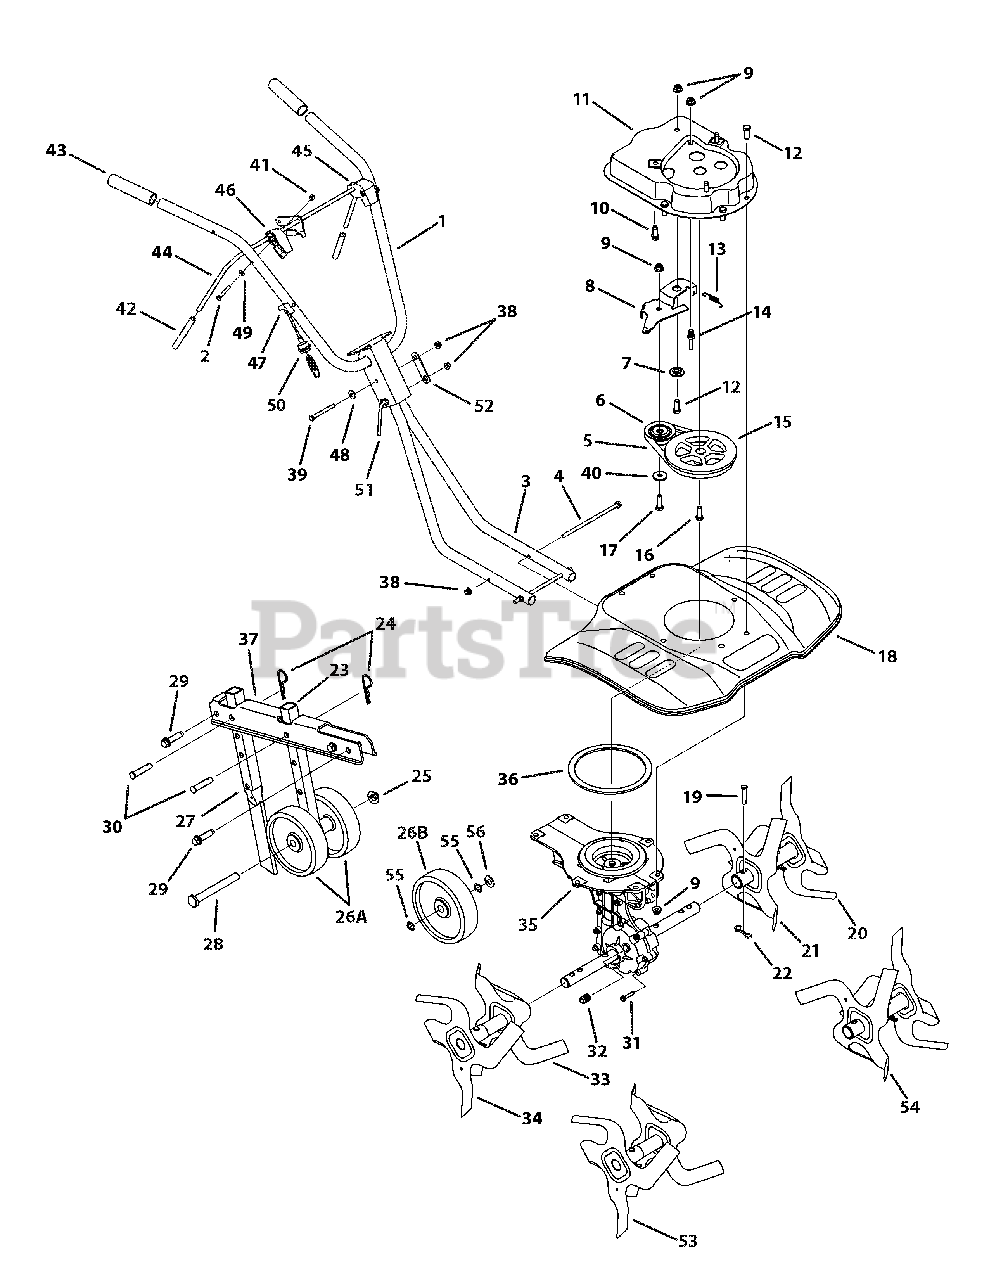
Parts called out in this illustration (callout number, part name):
1	Upper Handle
2	Hex Head Cap Screw, 1/4-20 x 1.75
3	Lower Handle
4	Flange Screw, 5/16-18 x 7.5, GR5
5	V-Belt
6	Idler Pulley
7	Shoulder Spacer
8	Idler Bracket
9	Flange Lock Nut, 3/8-16
10	Self Tapping Screw, 3/8-16 x 1.00
11	Belt Cover
12	Hex Head Cap Screw, 3/8-16 x 1.00
13	Extension Spring
14	Stud, 33 x 1.5, 3/8-16
15	Flywheel Pulley
16	Hex Head Cap Screw, 3/8-24 x 1.00
17	Hex Head Cap Screw, 3/8-16 x 1.55
18	Tine Shield 61 cm (model 240)
18	Tine Shield 40 cm (model 210)
19	Clevis Pin
20	Outer Tine Assbly LH (model 240)
21	Inner Tine Assbly LH (model 240)
22	Cotter Pin, Bow Tie
23	Rear Wheel Tube
24	Cotter Pin
25	Push Cap
26A	Wheel 5 x 1.38 (model 240)
26B	Wheel 6 x 1.50, Steel (model 210)
27	Depth Stake Tube
28	Axle Shaft
29	Self Tapping Screw, 3/8-16 x 1.50
30	Clevis Pin
31	Self Tapping Screw, 1/4-20 x 1.25
32	Pipe Plug, 1/4-18 NPT
33	Inner Tine Assbly RH (model 240)
34	Outer Tine Assbly RH (model 240)
35	Case Assembly
35	Case Assembly 40 cm (model 210)
36	Gasket
37	Wheel Bracket
38	Flange Lock Nut, 5/16-18
39	Hex Head Cap Screw, 5/16-18 x 3.00
40	Flat Washer, .406 x .875 x .059
41	Hex Lock Nut, 1/4-20
42	Handle Grip
43	Grip, 1.0 ID x 5.0 LG
44	Clutch Bail
45	Bail Holder LH
46	Bail Holder RH
47	Handle Fitting
48	Bell Washer, .340 x .872 x .060
49	Flat Washer, .25 x .630 x .0515
50	Clutch Cable
51	Handle Crank
52	Retainer Bracket
53	Tine Assembly RH (model 210)
54	Tine Assembly LH (model 210)
55	Wave Washer, .510 x .750 x .017
56	Flat Washer, .531 x .875 x .15
